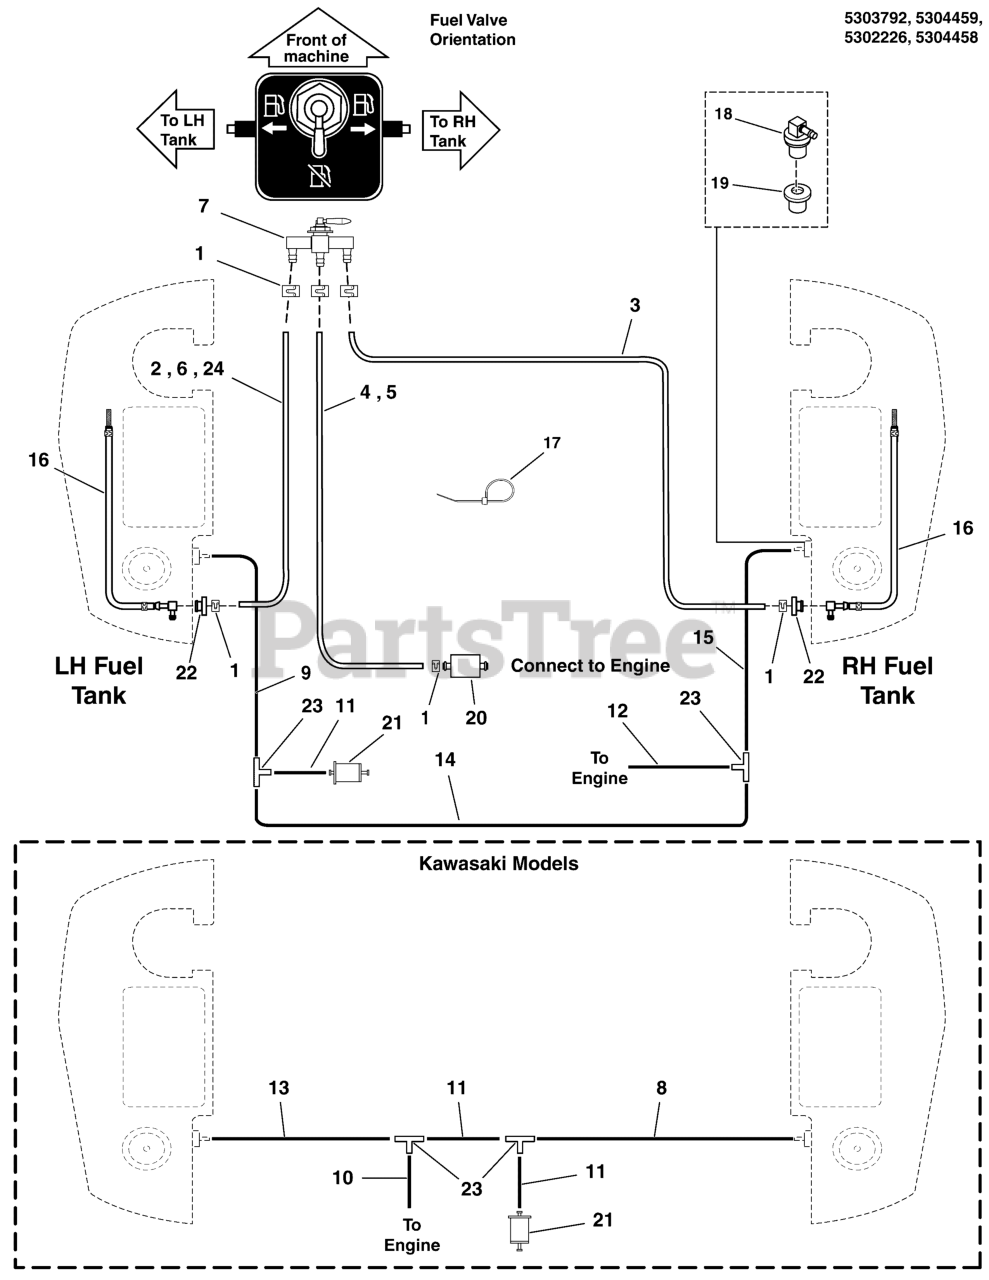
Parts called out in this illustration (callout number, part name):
1	CLAMP, HOSE, EXTERNAL, 1/2 - RED
2	HOSE, 1/4" FUEL, 15.50"
3	HOSE, 1/4" FUEL, 52.00"
4	HOSE, 1/4" FUEL, 34.00"
5	HOSE, 1/4" FUEL, 25.00"
6	HOSE, 1/4" FUEL, 22.00"
7	VALVE, FUEL SHUT-OFF, 11772
8	HOSE, VAPOR, 5MM ID, 39.00 LG
9	HOSE, VAPOR, 5MM ID, 21.50 LG
10	HOSE, VAPOR, 5MM ID, 32.00 LG
11	HOSE, VAPOR, 5MM ID, 2.00 LG
12	HOSE, VAPOR, 5MM ID, 9.00 LG
13	HOSE, VAPOR, 5MM ID, 16.00 LG
14	HOSE, VAPOR, 5MM ID, 15.00 LG
15	HOSE, VAPOR, 5MM ID, 25.00 LG
16	HOSE ASSEMBLY (SV)
17	TIE,SELF-LOCKING, 6"
18	REMOTE VENT ASSEMBLY
19	GROMMET (SV)
20	FUEL FILTER (SV)
21	FILTER, FUEL
22	BUSHING-FUEL TANK RED RUBBER
23	FITTING, 3/16" TEE, BARB TYPE, HDPE
24	HOSE, 1/4" FUEL, 25.00"
